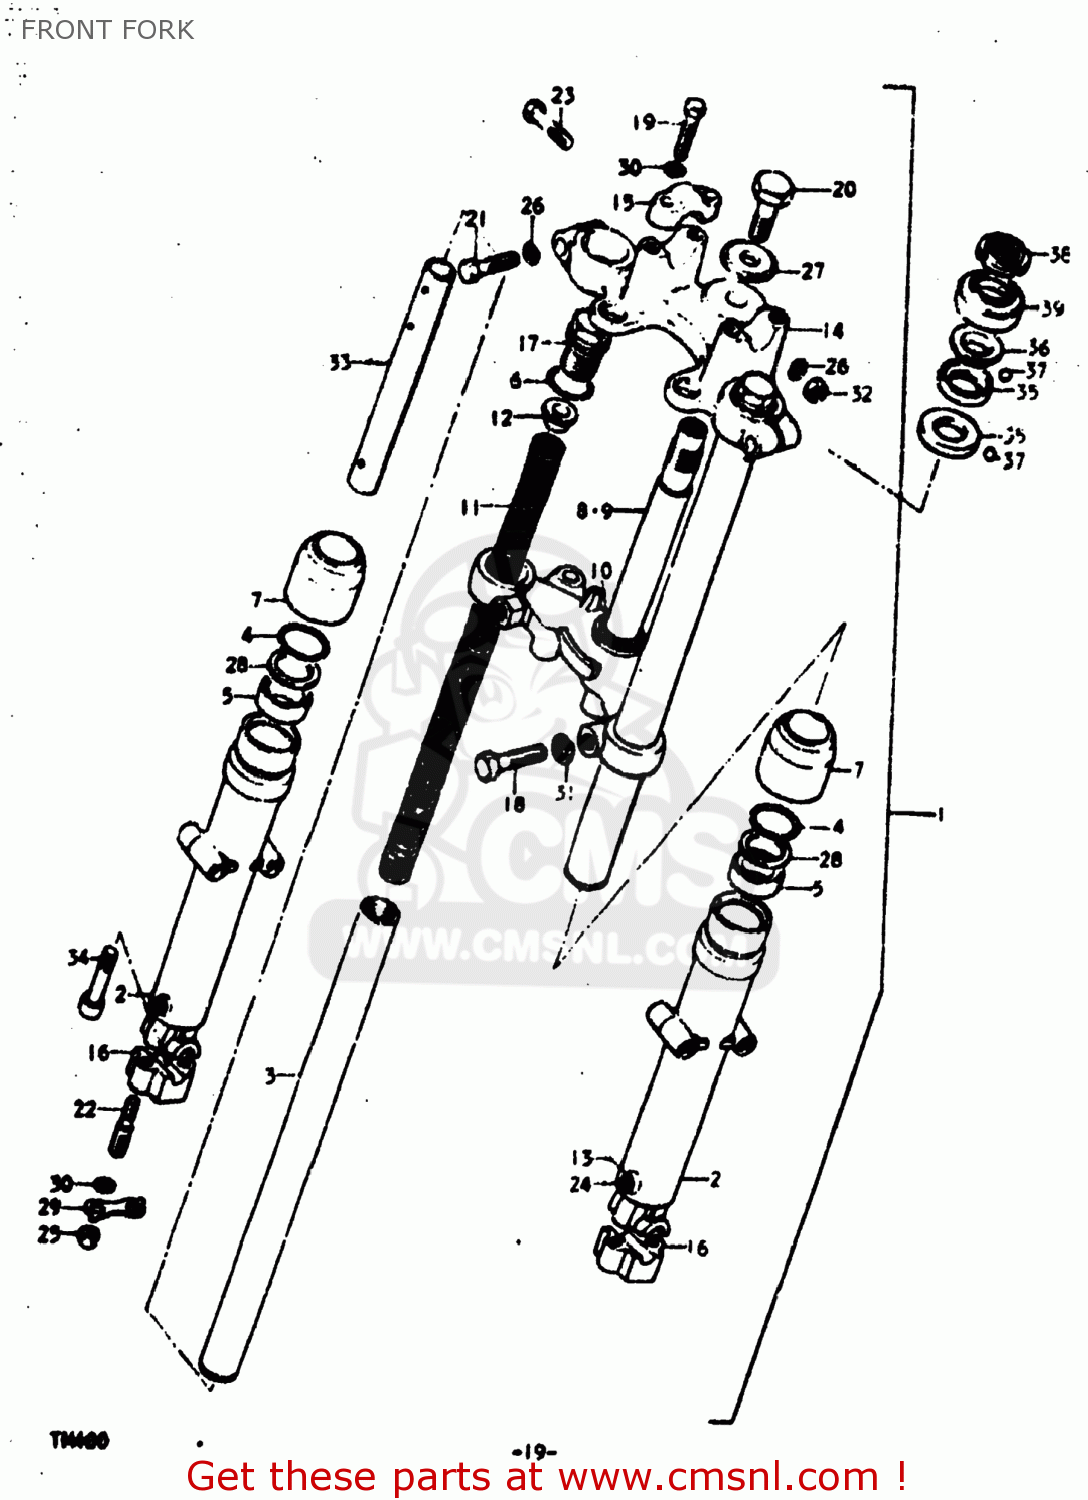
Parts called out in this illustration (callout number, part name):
0	DAMPER SET
1	TUBE,OUTER,RIGHT
2	TUBE,OUTER,LEFT
3	TUBE,OUTER,LEFT
4	SEAL,OIL
5	TUBE,FORK,INNER
6	CYLINDER,FRONT FORK
7	PIECE,OIL LOCK
8	CYLINDER,FRONT FORK
9	PIECE,OIL LOCK
10	GASKET (NAS)
11	BOLT,FORK CYLINDER(10X25)
12	STUD BOLT
13	HOLDER,AXLE
14	WASHER
15	LOCK WASHER
16	NUT (8MM)
17	CAP,FORK INNER TUBE
18	O-RING,FORK FITTING BOLT
19	SCREW
20	GASKET,DRAIN,PLUG (NAS)
21	SPRING
22	SPRING
24	SNAP RING
25	PISTON L
26	PISTON M
27	HEAD,STEERING STEM
28	BOLT
29	WASHER,STEM HEAD
30	CAP
31	HOLDER,HANDLEBAR
32	LOCK WASHER
33	Bolt
34	STEM,STEERING
35	STEM,STEERING
36	RACE,STEERING OUTER LWR
37	BOLT
38	LOCK WASHER
39	NUT
40	BOLT 10X50
41	LOCK WASHER
42	NUT
43	SEAL,DUST
44	BOLT
45	GUIDE,FRONT FORK SPRING
46	SEAT,FRONT FORK SPRING
47	CIRCLIP,FORK OIL SEAL
48	BOLT,STUD
49	WASHER
50	LACE,STEERING INNER LWR
51	LACE,STEERING OUTER UPR
52	BALL
53	NUT,STEERING STEM(25X44X10)
54	DUST SEAL,STEERING UPR
